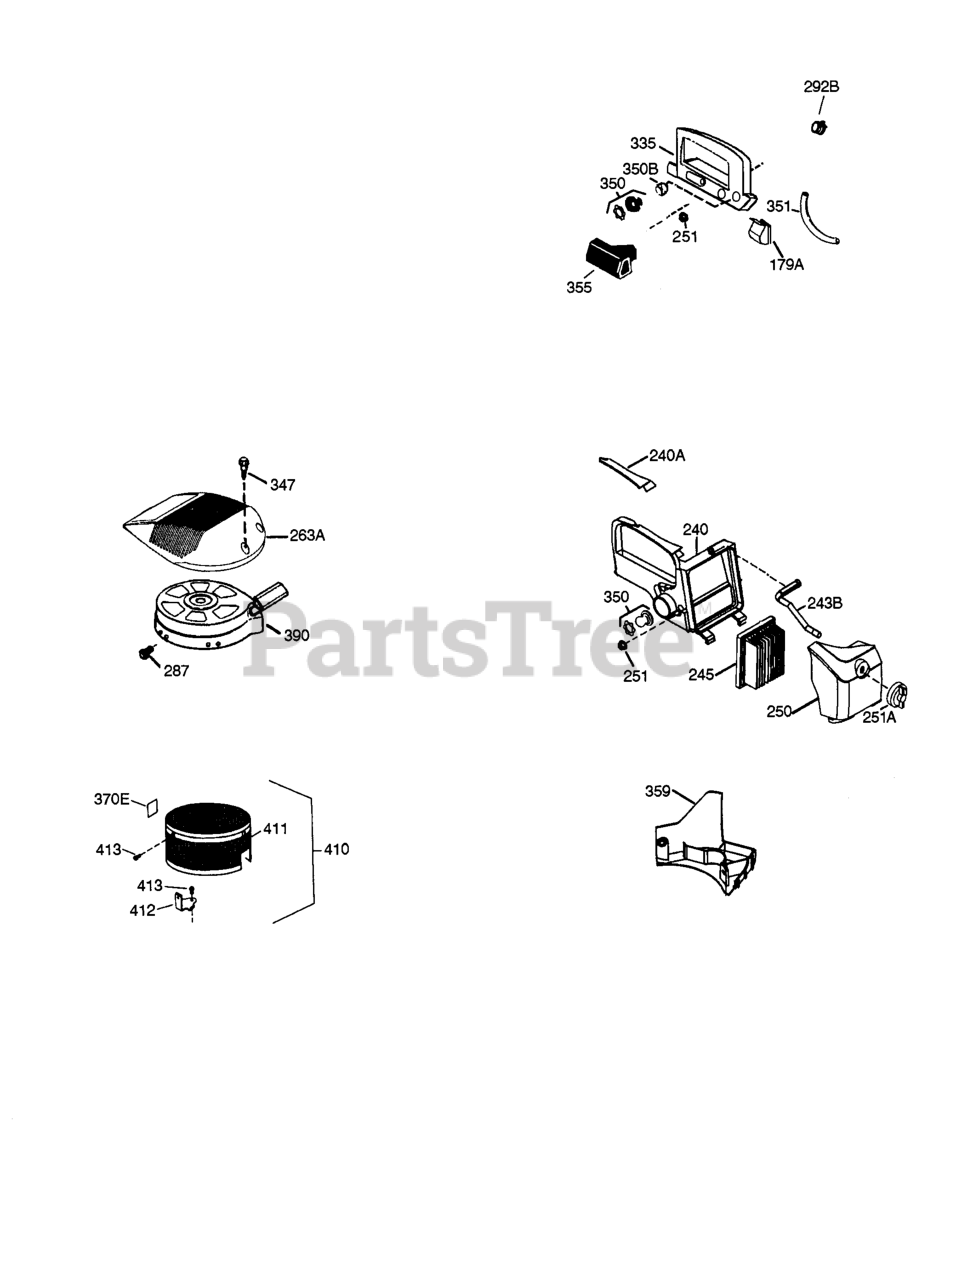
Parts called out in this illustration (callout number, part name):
187B	BAFFLE
240	CLEANER BODY
245	AIR CLEANER
250	CLEANER COV
263A	GRILLE
347	SCREW
350	PRIMER
390	STARTER
999	MAINTENANCE KIT
